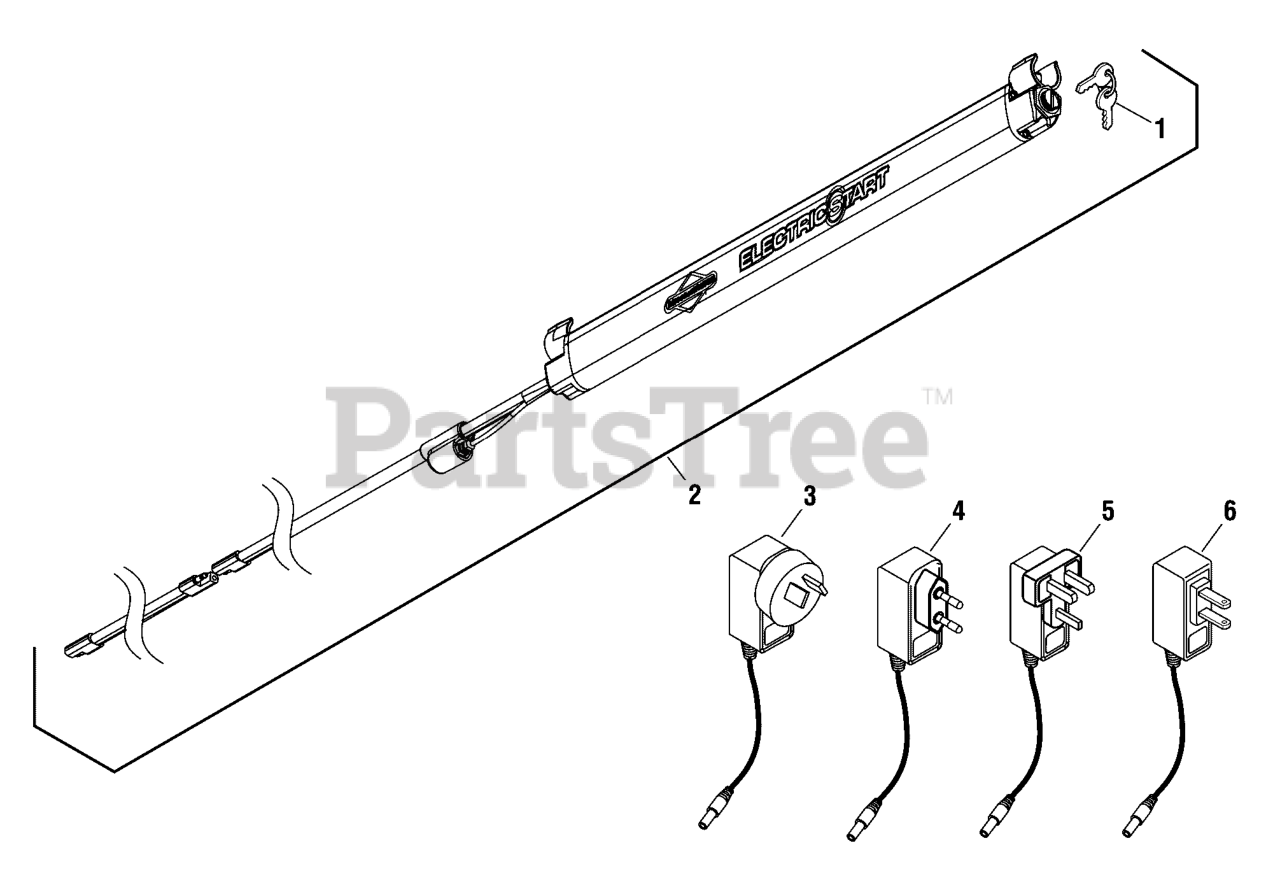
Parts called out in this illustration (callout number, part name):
1	KEY SET, Pair
2	BATTERY PACK, Keystart
3	CHARGER, Battery
4	CHARGER, Battery
5	CHARGER, Battery
6	CHARGER, Battery
